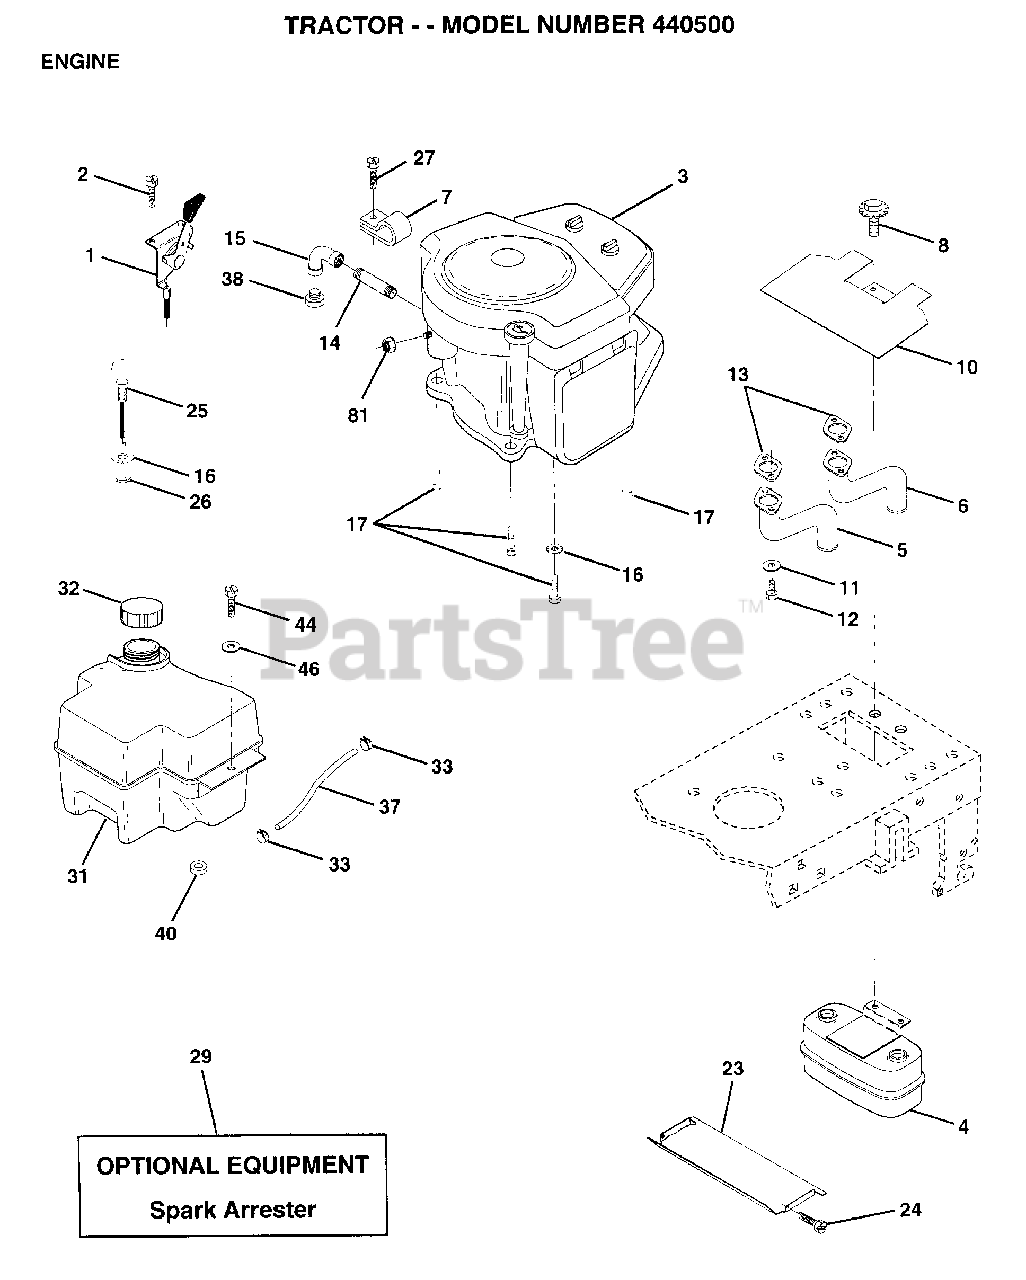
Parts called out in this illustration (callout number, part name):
1	CONTROL THRT 35.5
2	SCREW LT
4	MUFFLER.TW.LOTONE
5	EXHAUST.B&S.18.LH
6	EXHAUST.B&S.18.RH
7	CLAMP.TUBE.DBL.EN
8	BOLT.5/16-18.UNC
10	SHIELD.HEAT.
13	GASKET MUFFLER
14	PIPE NIPPLE LT
15	ELBOW
16	LOCKWASHER
17	SCREW LT
23	HEAT SHIELD
24	SCREW
25	CONTROL.CHOKE.37
26	"NUT,KEPS 3/8-24IM"
27	SCREW.10-24X1/2
29	SPRING.COMP.INF.H
32	CAP ASM FUEL
33	HOSE CLAMP
37	LINE FUEL
44	SCREW HEX CRT
49	WASHER
81	NUT
